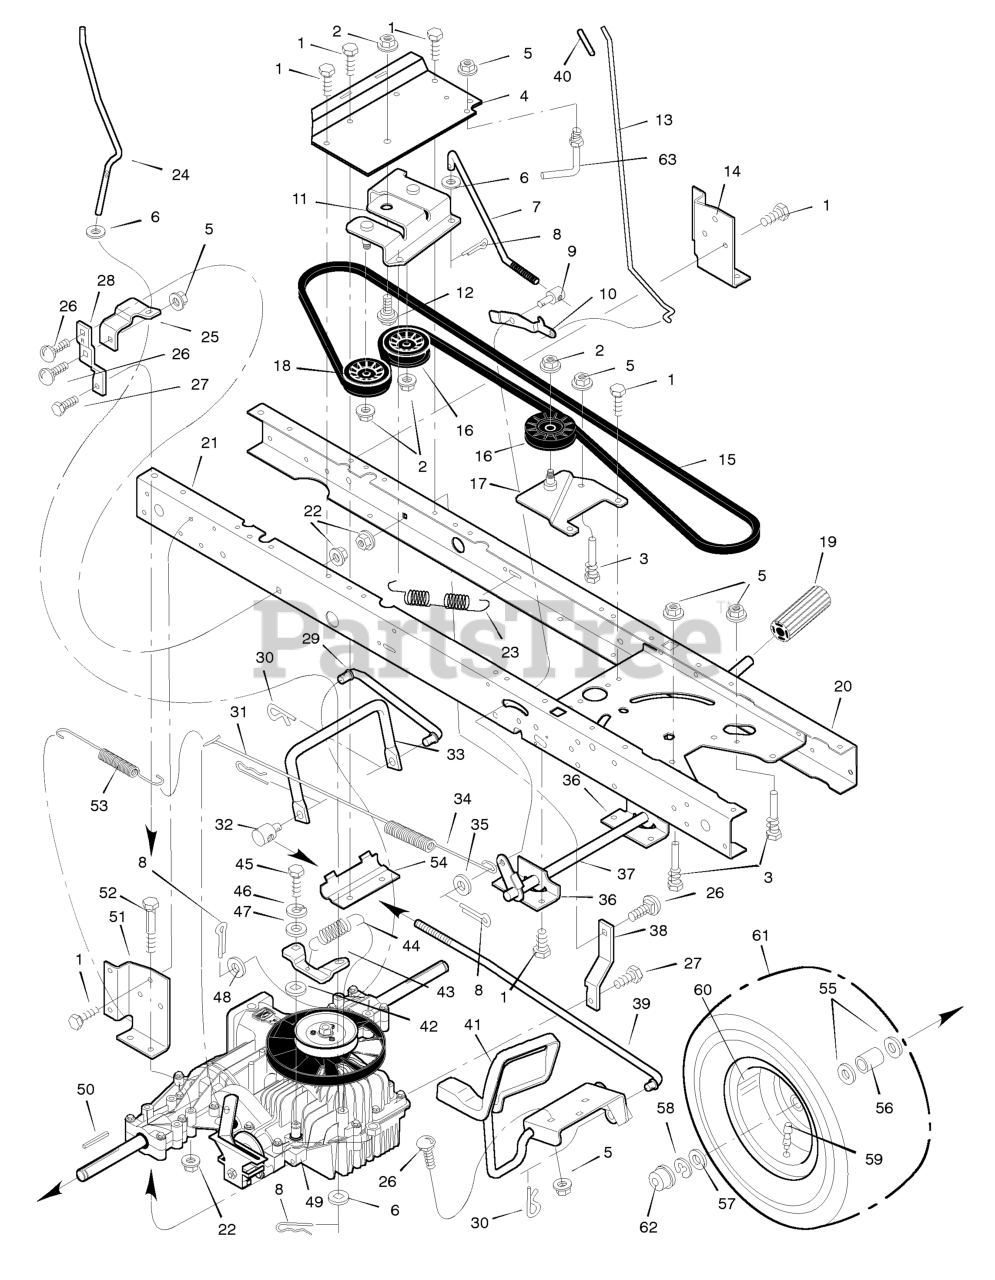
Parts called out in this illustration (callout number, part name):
2	Nut, Flange
3	Guide, Belt
4	Bracket, Idler
5	Locknut
6	Washer
7	Rod, Clutch
8	Pin, Cotter
9	Adjuster
10	Latch, Parking Brake
11	Bracket Assembly, Idler
12	Bolt, Shoulder
13	Rod, Parking Brake
14	Bracket, Transaxle
16	Pulley, Idler
17	Arm Assembly, Idler
18	Pulley, Idler
19	Pedal
20	Frame, Left
21	Frame, Right
22	Nut, Flange
23	Spring, Extension
24	Rod, Disconnect
25	Bracket, Disconnect
26	Bolt, Carriage
28	Strap, Right Torque
29	Rod, Link
30	Pin, Hair
31	Pin, Hair
32	NUT, Adjusting, 1/2-13
33	Rod, Yoke
34	Spring, Extension
35	Washer
36	Bracket, Pivot
37	Lever, Clutch/Brake
38	BRACKET, Torque Strap, LH
39	Rod, Link
41	Pedal, Speed Control
43	Arm, Disconnect
44	Spring
46	Lockwasher
48	Washer
49	Transaxle **
50	Key, Square
51	Bracket, Right Transaxle
52	Bolt
53	Spring, Extension
54	Clamp, Transaxle
59	Valve Stem
60	Wheel & Tire Assembly
61	Tire *
62	Cap, Hub
63	Guide, Belt
